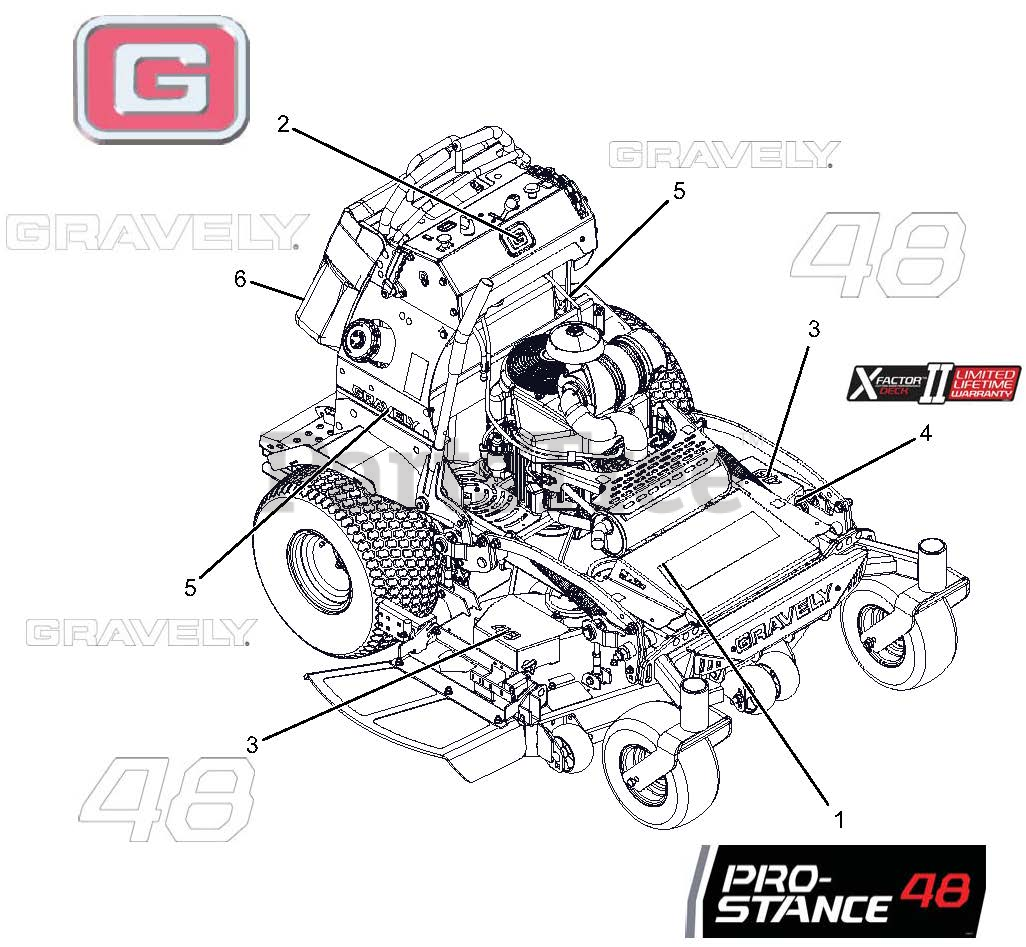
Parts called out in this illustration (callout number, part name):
1	DECAL, PROSTANCE 48
2	DECAL, GRAVELY BRAND
3	DECAL, 48"
4	DECAL, X-FACTOR DECK
5	DECAL, 9.5" GRAVELY LOGO
6	DECAL, 13.5" GRAVELY LOGO
